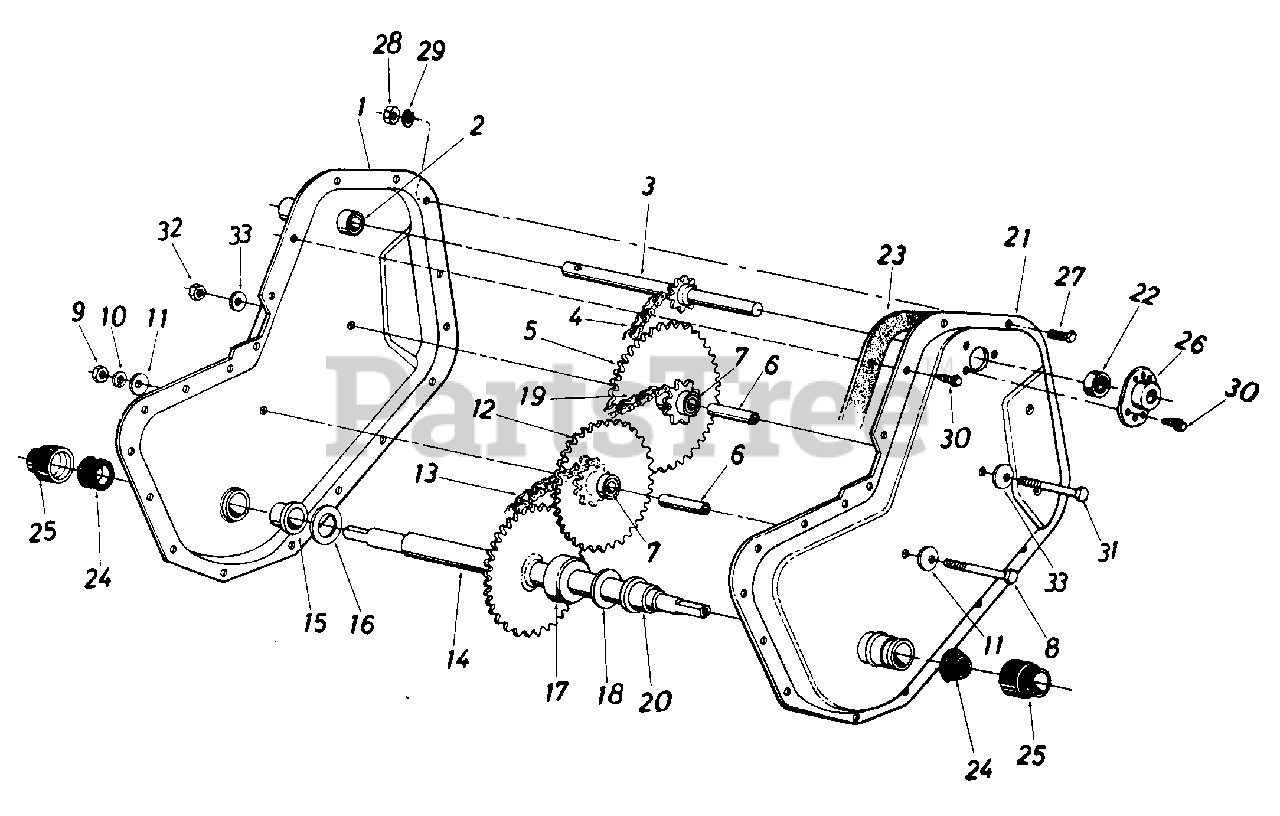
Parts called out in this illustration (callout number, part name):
1	Chain Case Half Ass'y.-R.H.
2	Bearing 5/8n I.D. x .813" O.D. x 1.31" Lg.
3	Input Shaft Ass'y.
4	Chain #35-3/8" Pitch x 44 Link
5	Sprocket and Hub Ass'y.
6	Bearing Inner Axle
7	Sleeve Brg. 5/8" I.D. x 3/4" O.D. x 1.50
8	Hex Bolt 3/8-24 x 2.50" Lg.
9	Hex Ins. L-Nut 3/8-24 Thd.
10	L-Wash. 3/8" I.D.
11	Bell-Wash. .41" I.D. x 1.13" O.D. x .03
12	Sprocket & Hub Ass'y. 9T-22T
13	#420 Chain 1/2 Pitch x 28 Links Endless
14	Wheel Shaft Ass'y.
15	Flange Bearing
16	Fl-Wash. .88" I.D. x 1.5" O.D. x .03
17	Spacer 7/8" I.D. x 13/4" O.D. x.68" Lg.
18	Fl-Wash. .88" I.D. x l.50" O.D. x .03
19	#420 Chain 1/2" Pitch x 30 Links Endless
20	Flange Bearing
23	Gasket
25	Dust Cup
26	Bearing Housing
27	Hex Bolt 1/4-28 x 5/8" Lg.
28	Hex Nut 1/4-28 Thd.
29	L-Wash. 1/4" I.D.*
30	Hex Wash. S-Tap Scr. 1/4-20 x 50" Lg
31	Hex Bolt 5/16-18 x 2 5" Lg.
32	Hex Cent. L-Nut 5/16-18 Thd.
33	Fl-Wash. 5/16" I.D.
